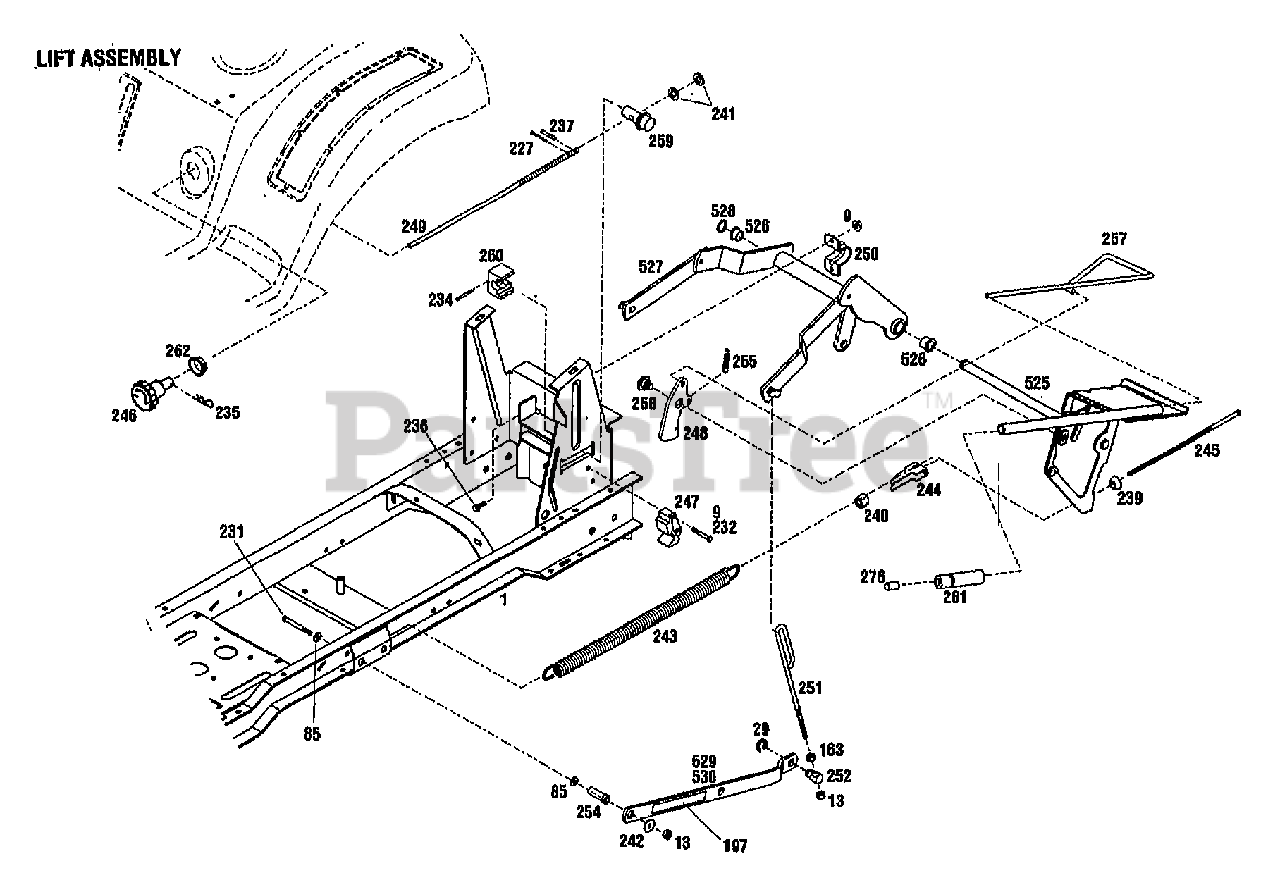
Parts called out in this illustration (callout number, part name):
9	NUT-HFLK 5/16-18 ZP
13	NUT-LOCK 3/8-16
29	RING-RETAINING
85	WASHER-FLAT 3/8 SAE
163	NUT-HEX 3/8-16 ZP
197	DECAL-WARNING
227	PIN-COTTER .125 X .75 ZP
231	SCR-HH 3/8-16X3.0 G5 ZP
232	SCR-HH 5/16-18X1.5 G5 ZP
234	PIN-DRIVE {13097}
235	PIN-HITCH {13097}
236	SCR-HFLK 5/16-18X.75 ZP
237	PIN-ROLL .156X1.0 {13097}
239	BEARING-SPHERICAL
240	NUT-SPECIAL 5/16-18
241	SPACER {13097}
242	WASHER-1.5X.375X.18 ZP
243	SPRING-LIFT ASSIST
244	BRKT-LIFT ASSIST
245	SCR-LIFT ASSIST
246	KNOB-HEIGHT ADJUST {13097}
247	BLOCK-DETENT
249	KIT-SVC SCR HGT ADJ {13097}
250	CLAMP-LIFT
252	SWIVEL-REAR LIFT
254	SPACER
255	SPRING-EXTENSION
256	SCR-SHOULDER
259	BLOCK-HEIGHT ADJUST {13097}
260	COLLAR-HEIGHT ADJUST {13097}
261	GRIP-LIFT
262	GROMMET-SNAP BUSHING {13097}
276	BUTTON-LIFT
525	HANDLE-LIFT
528	RING-RETAINING EXT .694 ID
529	LINK-LIFT W/DECAL
530	LINK-LIFT W/DECAL
